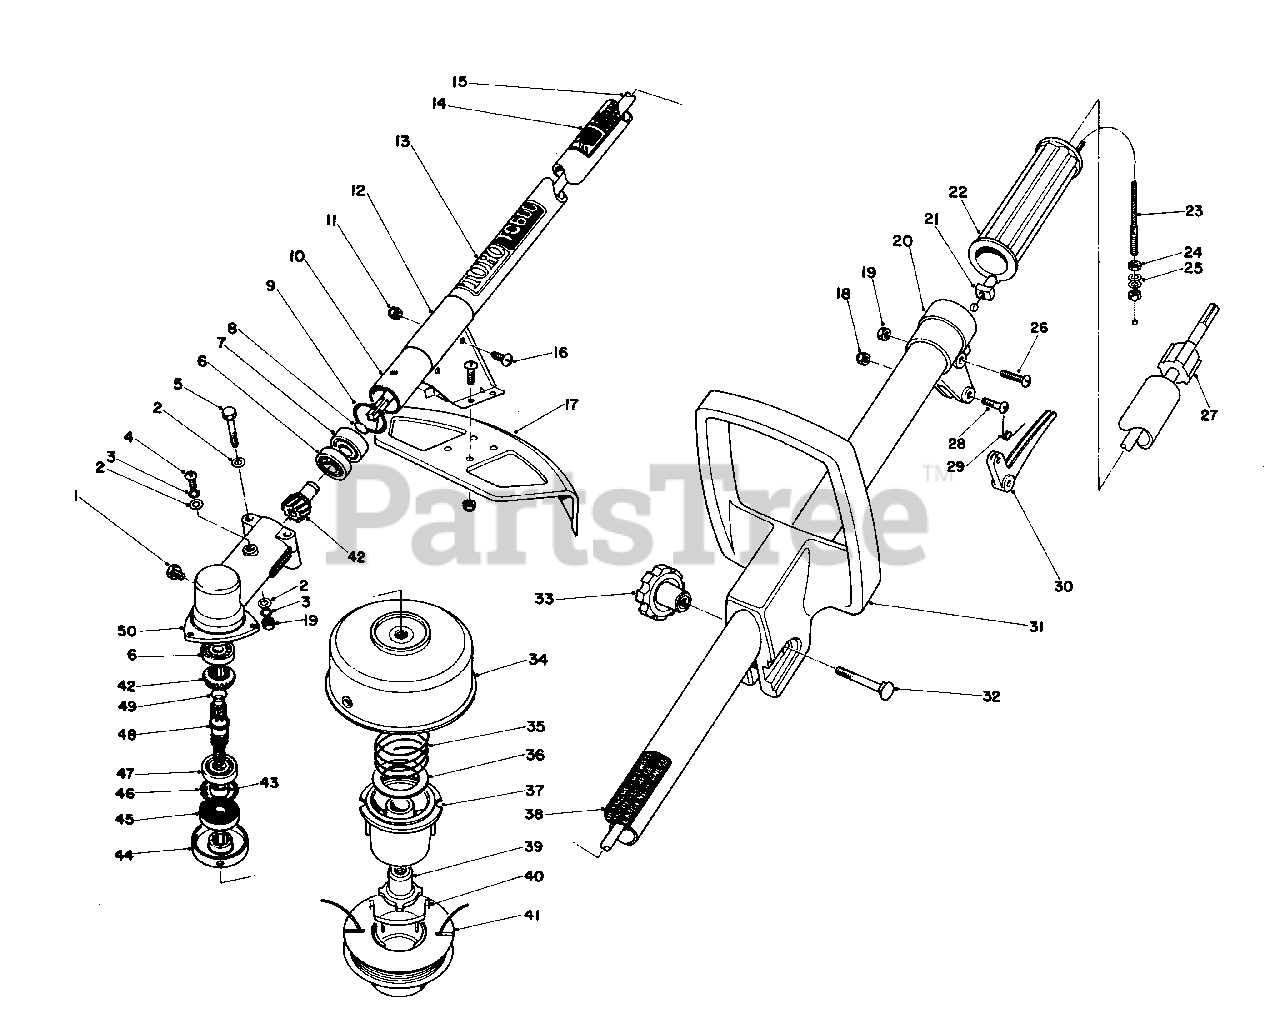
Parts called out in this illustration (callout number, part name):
3	Spring Washer
6	Ball Bearing
7	Ball Bearing
10	Housing Assembly
12	Bracket Shield
13	Decal-TC 600
14	Decal Warning
15	Shaft Drive
16	Screw Rd. Hd.
19	Nut
20	Bracket, Trigger
23	Throttle Cable
25	Washer
29	Spring Return
30	Throttle Trigger
31	Adjustable Handle
32	Carriage Bolt
34	Drum Assembly
35	Spring-Compression
37	Spool Core
40	Saddle-Spool Cap
41	Prewound Spool
42	Gear Set
44	Plate, Blade Fixing
45	Oil Seal
47	Ball Bearing
48	Shaft P.T.O.
50	Gear Housing
